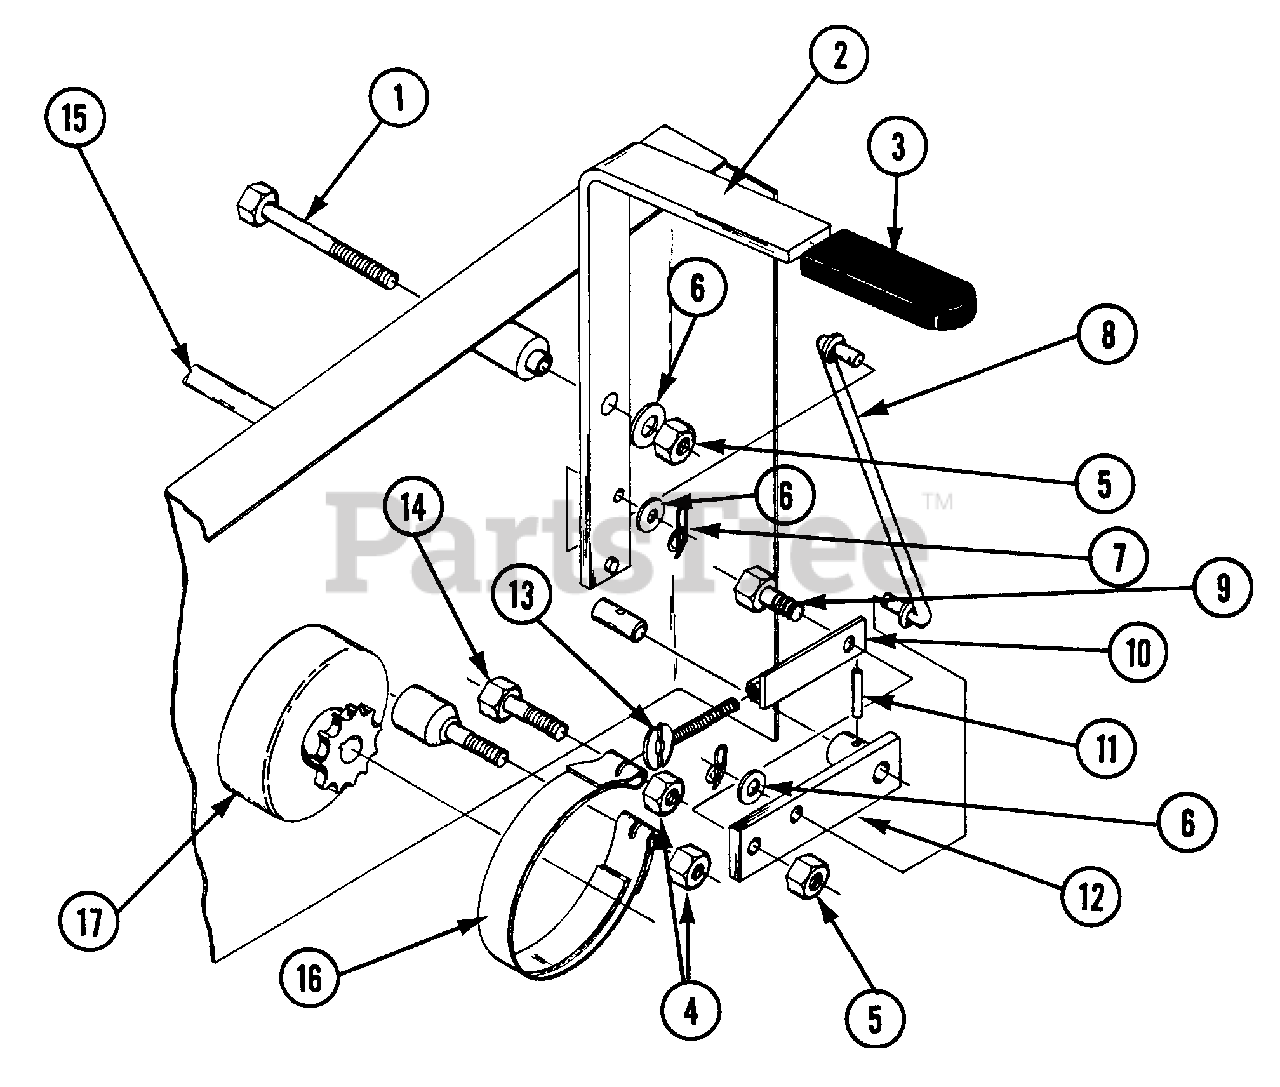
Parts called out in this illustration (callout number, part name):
1	CAPSCREW, HEX, 5/16-18 X 3, GRADE 5
2	BRAKE HANDLE WELDMENT
3	GRIP, DIPPED VINYL, 1/4 X 1
4	LOCKNUT, HEX, 3/8 -16, W/NYLOC
5	LOCKNUT, HEX, 5/16-18, W/NYLOC
6	WASHER, 5/16 STD, FLAT
7	COTTER, RUE RING, 5/16-3/8 PIN
8	BRAKE-ROD LINK WELDMENT
9	CAPSREW, HEX, 5/16-18 X 1, GRADE 5
10	BRAKE LINK WELDMENT
11	PIN, SPIROL, 3/16 X 1, LIGHT DUTY
12	BRAKE ARM WELDMENT
13	THUMBSCREW SWIVEL
14	CAPSCREW, HEX, 3/8-16 X 1-1/2, GRADE 5
15	BRAKE CROSS SHAFT
16	BRAKE BAND, 4-3/16 DIA, 3/4 WIDE
17	SPROCKET/BRAKE DRUM WELDMENT
